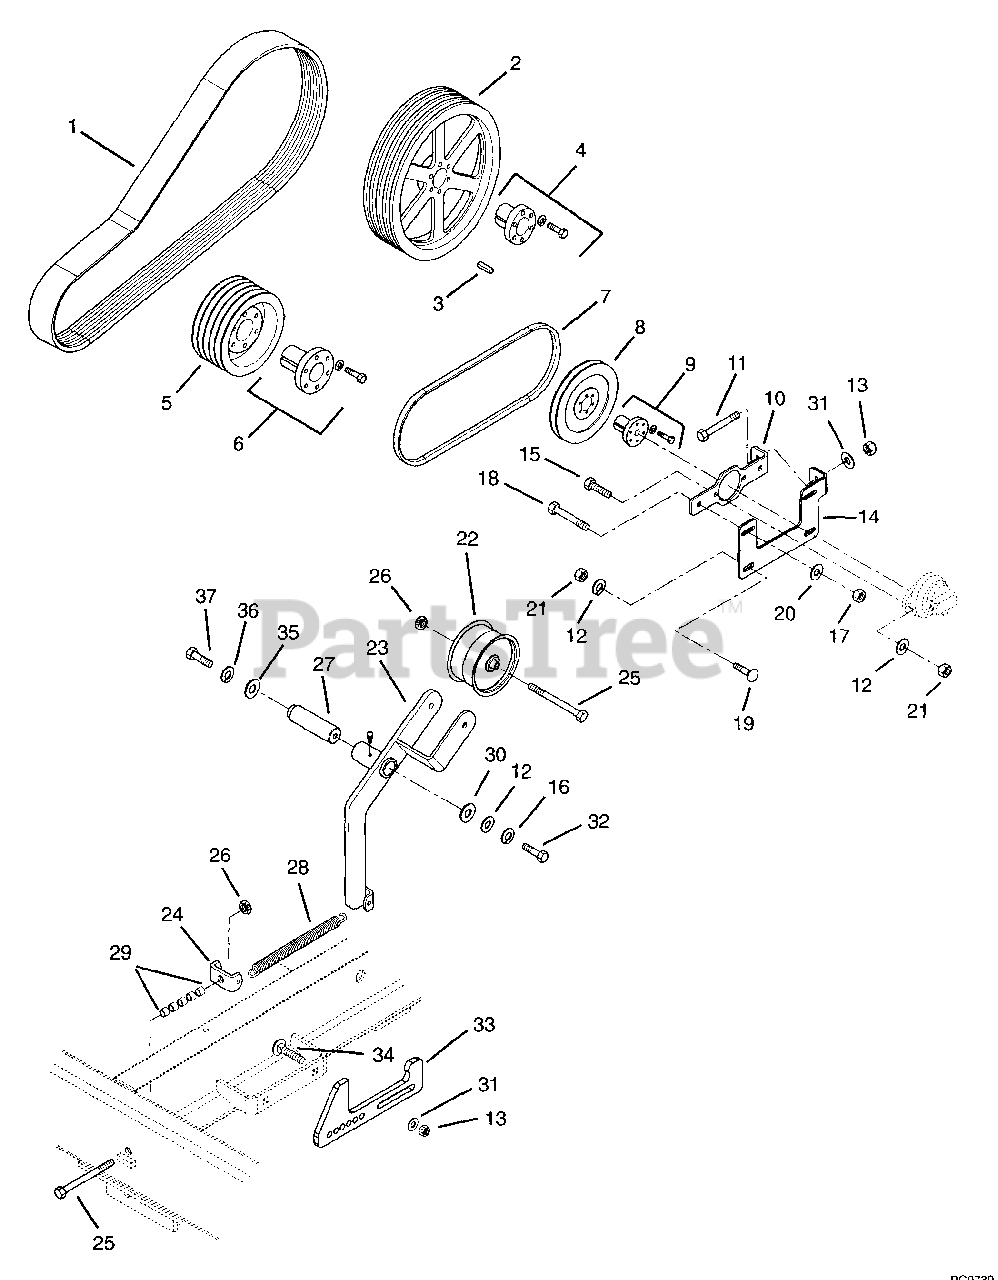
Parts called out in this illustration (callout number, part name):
1	V-Belt-4 Groove Banded
2	Pulley Driven 16 in
3	Key-Straight .50 x .50 x 1.75
4	Bushing-Sheave
5	Drive Sheave
6	Bushing-Sheave
6	Bushing-2.250 Bore w/.625 Key
8	Pump Sheave
9	Bushing-Sheave
10	Hydraulic Pump Bracket
11	Bolt-Hex .375-16 x 3.00 Grade 5
12	Washer-Flat-Steel .438 x 1.25 x .083
13	Nut-Locking-Center .38-16
14	Hydraulic Pump Mount Bracket
15	Bolt-Hex .44-14 x 1.25 Grade 5
16	Washer-Lock .44 x .109
17	Nut-Locking-Center .50-13
18	Bolt-Hex .50-13 x 3.00 Grade 5
19	Bolt-Round Head Square Neck .44-14 x 1.50
20	Washer-Flat-Steel .563 x 1.38 x .109
21	Nut-Locking-Center .44-14
22	Pulley-Idler
23	Idler Arm Weldment
24	Spring Bracket
25	Bolt-Hex .50-13 x 6.00 Grade 5
26	Nut-Locking .50-13
27	Shaft-Idler Arm Pivot
28	Spring-Tension .156 x 1.062 x 2.68
29	Spacer-Idler Spring
30	Washer-Flat-Steel .511 x 1.441 x .125
31	Washer-Flat-Steel .438 x 1.00 x .083
32	Bolt-Hex .44-14 x 1.50
33	Stop-Idler Arm
34	Bolt-Round Head Square Neck .38-16 x 1.25 Grade 2
35	Washer-Flat-Steel .812 x 2.00 x .148
36	Washer-Locking .75 x .188
37	Bolt-Hex .75-10 x 1.50 Grade 5
